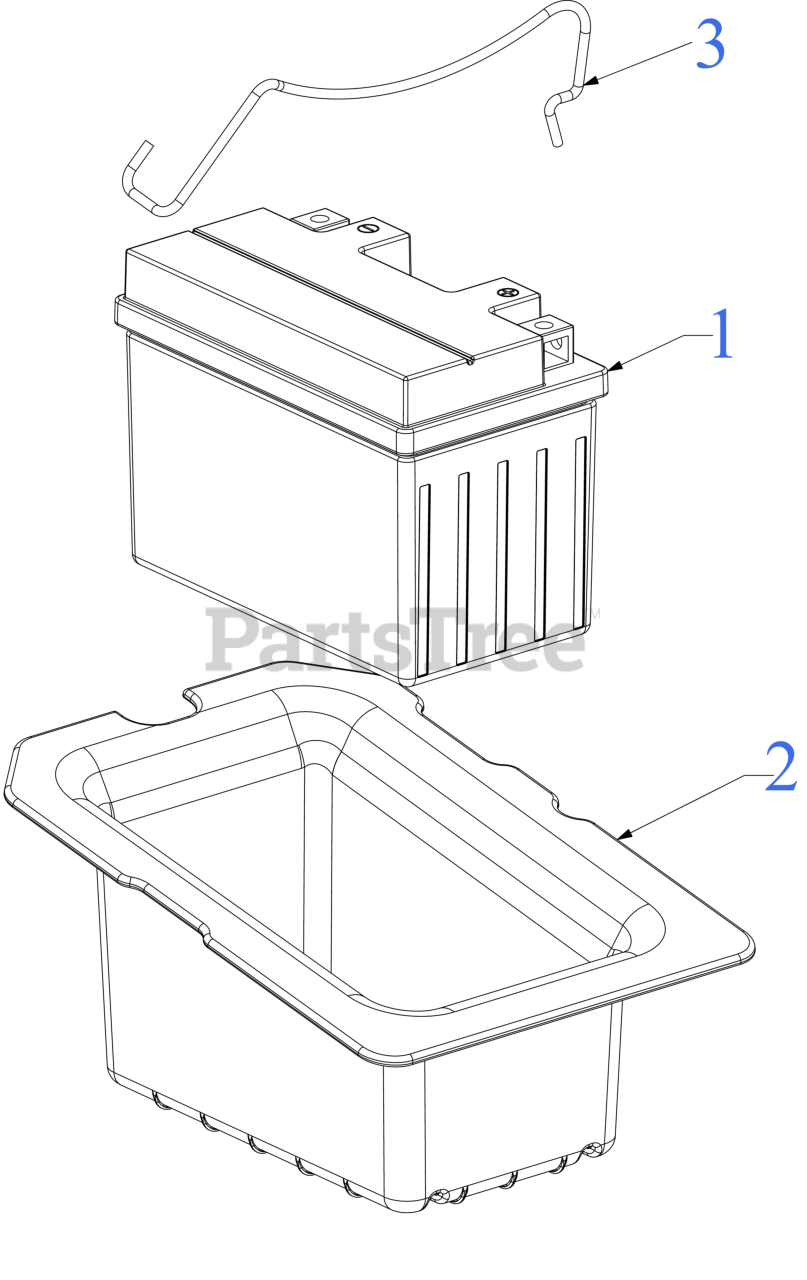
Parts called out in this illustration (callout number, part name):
1	BATTERY (11AHR AGM 210CCA)
2	BATTERY TRAY
3	BATTERY HOLD DOWN ROD
